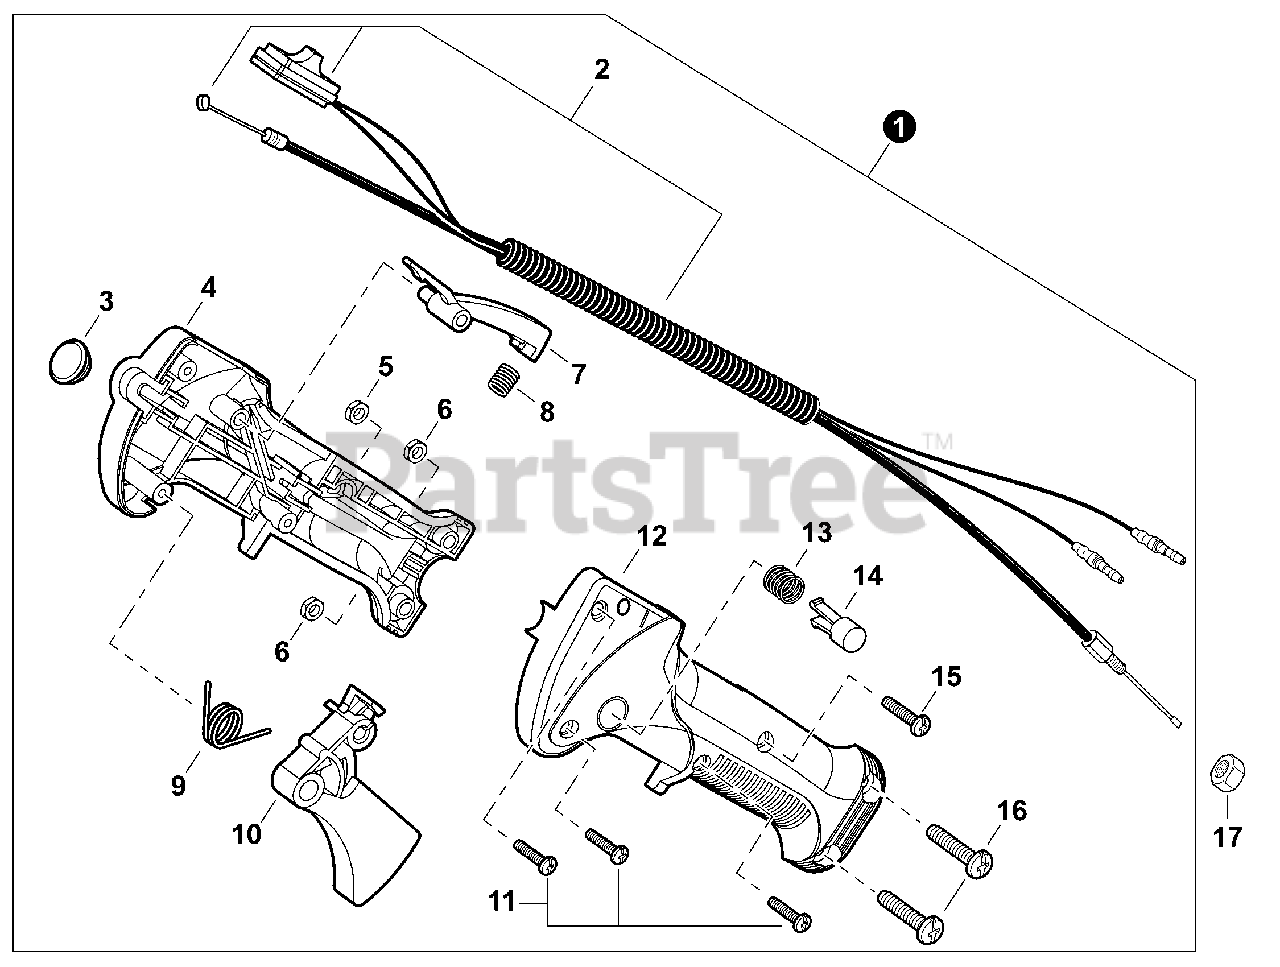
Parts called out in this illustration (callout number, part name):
1	CONTROL HANDLE ASSY
2	CABLE ASSY, CONTROL
3	PLUG, RUBBER
4	CONTROL HANDLE - RIGHT
7	LOCKOUT, THROTTLE
8	SPRING, COMPRESSION
9	SPRING, TORSION
10	TRIGGER, THROTTLE
11	SCREW, TAPPING 4×16
12	CONTROL HANDLE - LEFT
13	SPRING, COMPRESSION
14	BUTTON, THROTTLE LOCK
15	SCREW M4×23
16	SCREW M5×20
